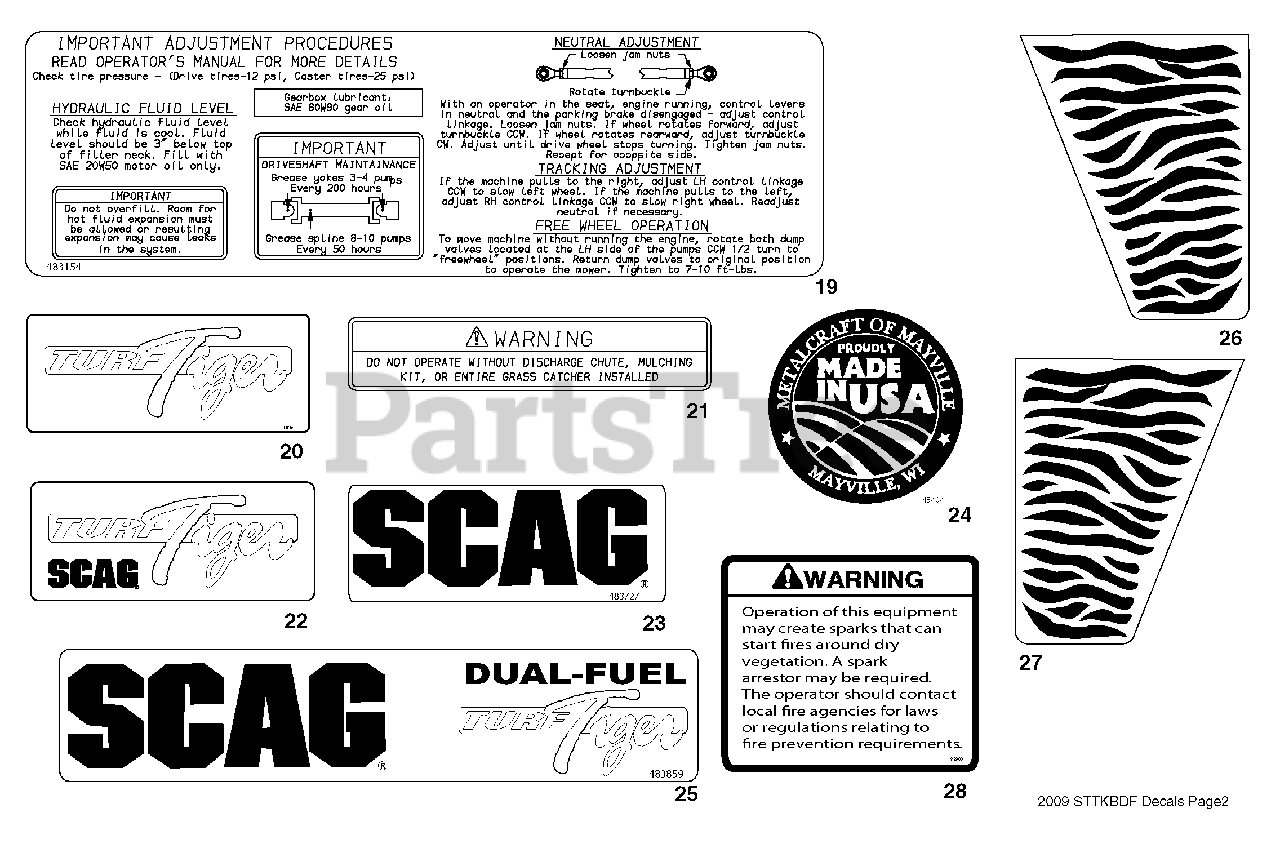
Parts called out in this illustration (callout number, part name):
19	Decal, Checks and Adjustments
20	Decal, Turf Tiger
21	Decal, Warning
22	Decal, Turf Tiger
23	Decal, Scag Logo
24	Decal, Metalcraft-Made In USA
25	Decal, Scag Dual-Fuel
26	Decal, Stripes-RH
27	Decal, Stripes-LH
28	Decal, Warning Spark Arrestor
